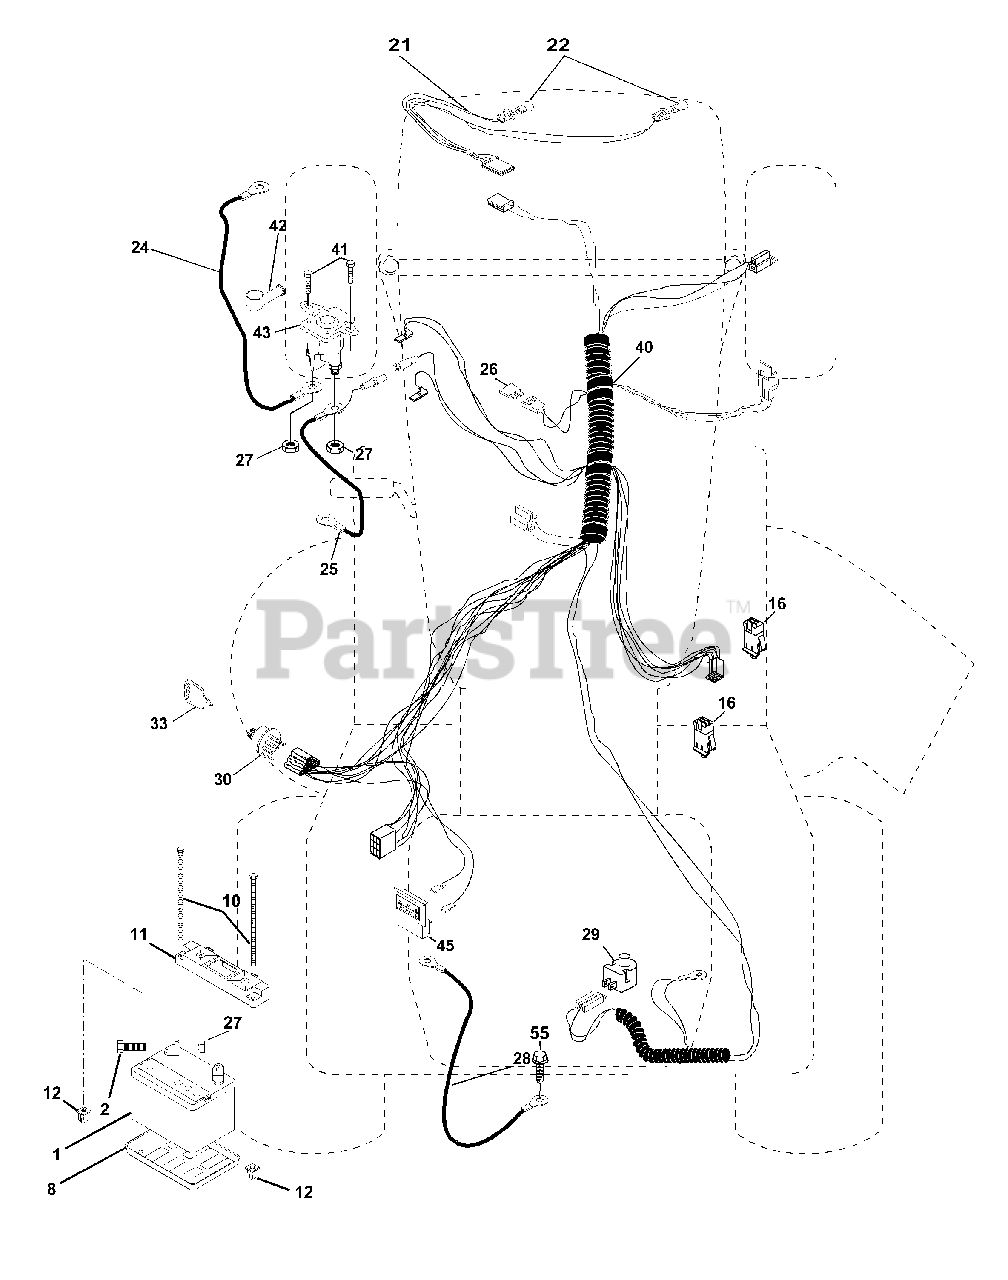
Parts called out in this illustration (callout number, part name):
1	Battery, 12 Volt, 28 Amp
2	Bolt, Hex Head 1/4-20 UNC x 3/4
8	Tray, Battery
10	Bolt, Battery Front 1/4-20 x 7.5 Zinc
11	Holddown Battery Dash Mount
12	Nut, Push Nylon 1/4" Battery Front
16	Switch Interlock Push-In
21	Harness, Light
22	Bulb, Light
24	Cable, Battery, 6 Gauge, 11", Red
25	Cable, Battery
26	Fuse, 20 Amp
27	Nut, Hex, Keps 1/4-20 UNC
28	Cable, Ground, 6 Gauge, 12", Black
29	Switch, Plunger
30	Switch, Ignition, Push-In
33	Key, Ignition
40	Harness, Ignition
41	Bolt, Hex, Fin. 1/4-20 x 1/2
42	Cover, Terminal, Red
45	Ammeter, Rectangular
55	Screw, Thdrol 5/16-18 x 1/2 TYT
